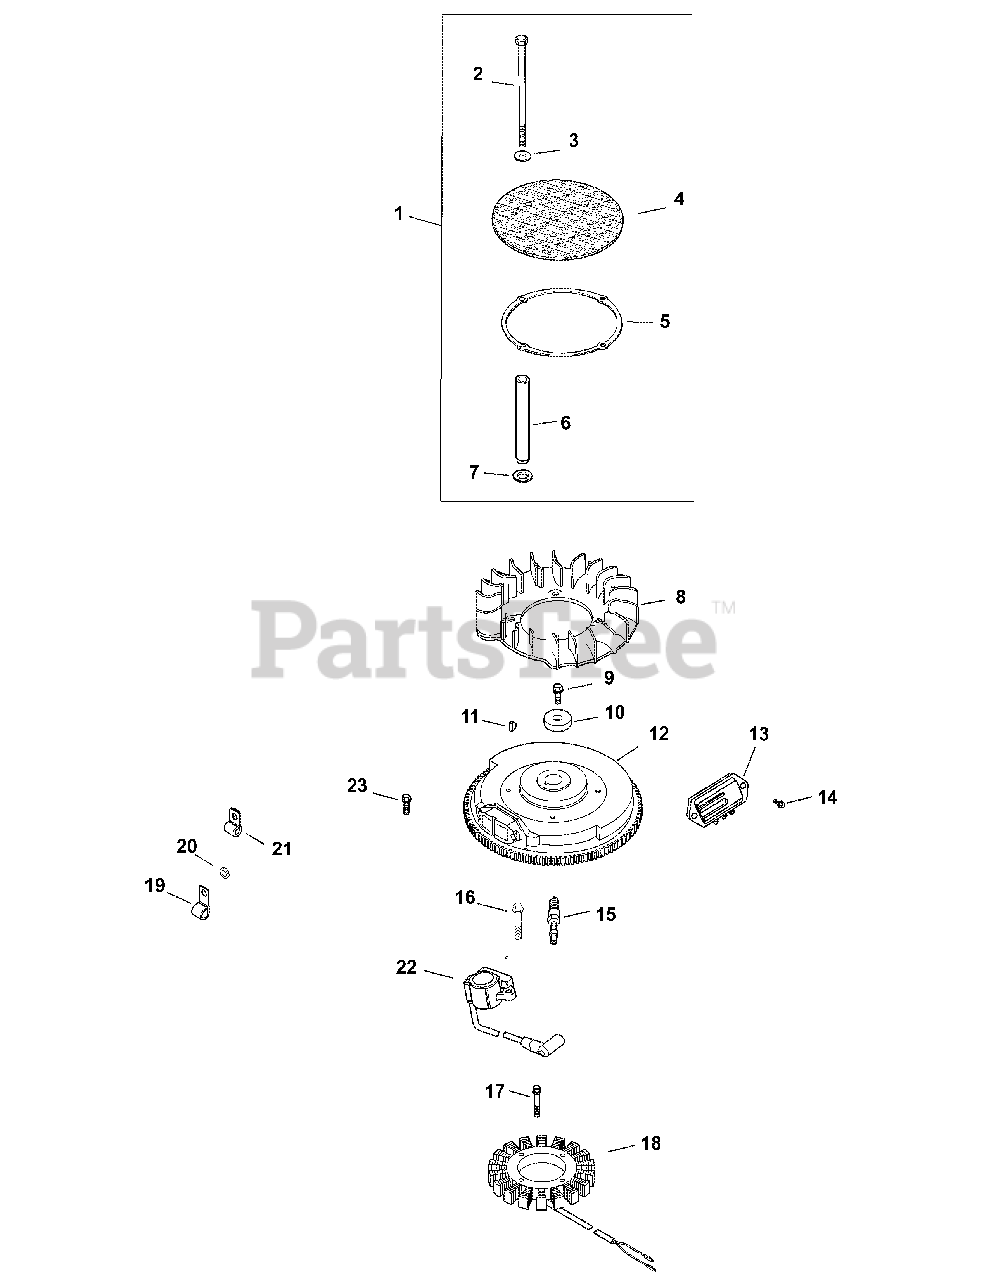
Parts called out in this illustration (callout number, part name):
1	KIT, CHOPPER SCREEN
2	SCREW, CAP M6X1.0X99.5
3	WASHER, FLAT 1/4"
4	SCREEN, GRASS
5	RING, SUPPORT
7	WASHER, SPRING 10 MM
9	SCREW, FLG M10X1.5X45
10	WASHER, FLAT 13/32"
11	KEY, 3/16" X 5/8"
13	REGULATOR/RECTIFIER
14	SCREW, PHL HD #11-16X7/8"
15	PLUG, SPARK
16	SCREW, THD FRM M5X0.8X25
17	SCREW, SKT SET #10-24X1/4"
18	KIT, 15 AMP STATOR
19	CLAMP, INSULATED
20	WASHER, FLAT 1/4"
21	CLIP, CABLE
22	MODULE SPARK ADV (DSAI) ASSY
23	SCREW, FLG THD FRM M5X0.8X20
